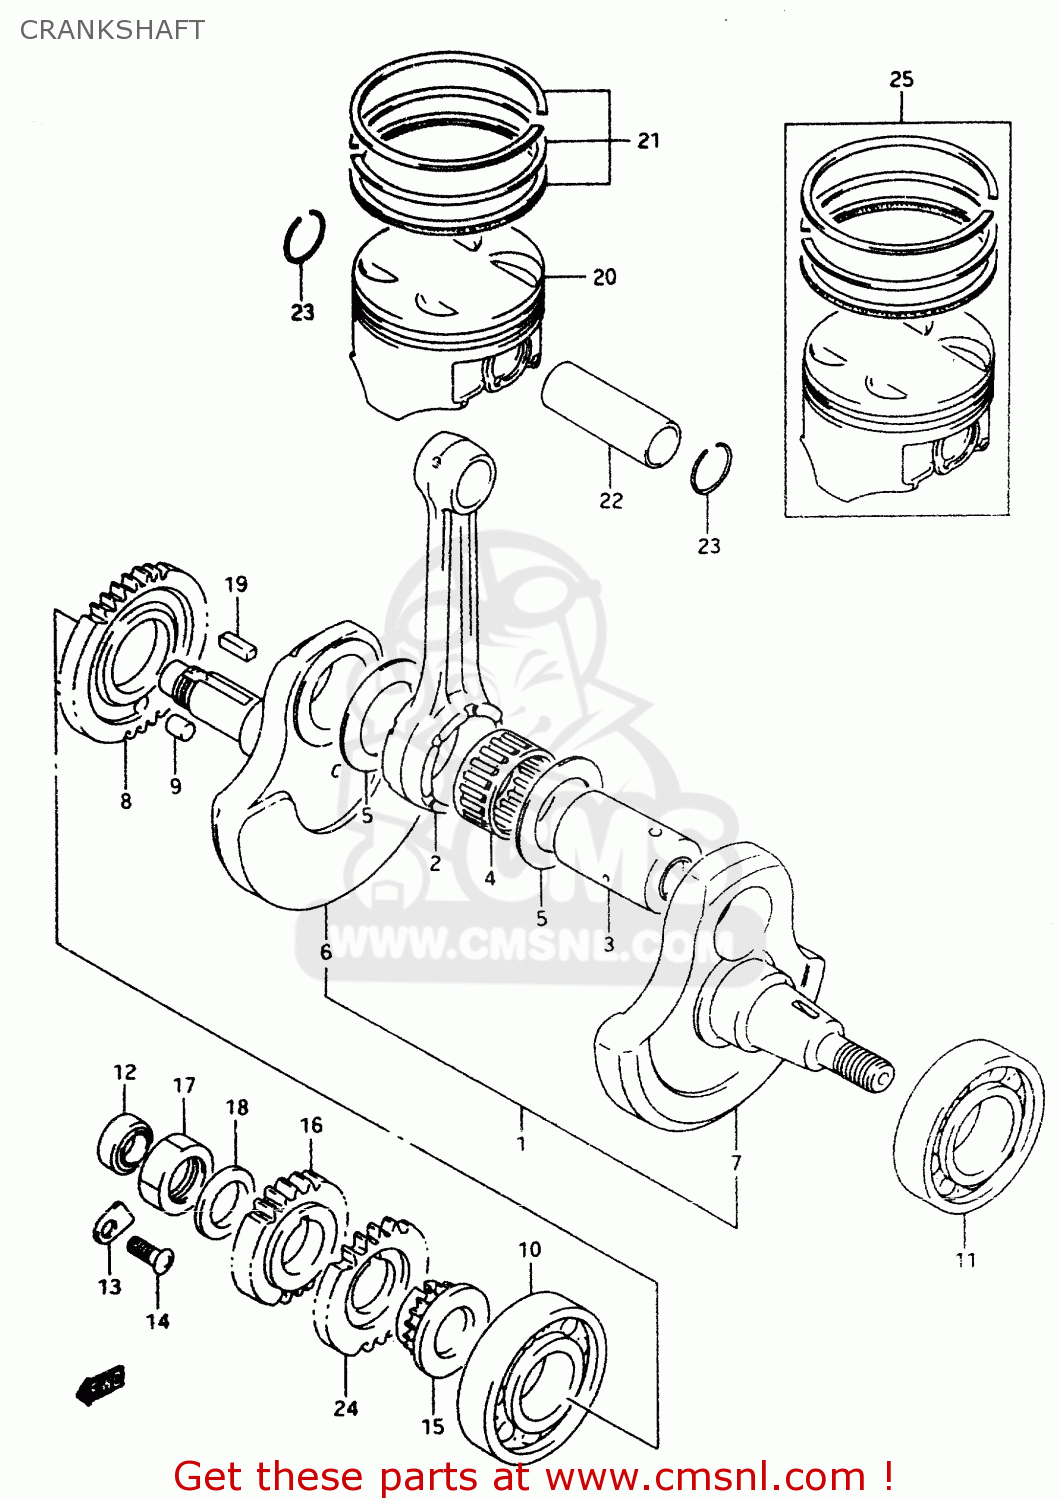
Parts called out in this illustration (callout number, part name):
1	CRANKSHAFT ASSY
2	ROD,CONNECTING
3	PIN COMP,CRANK
4	BEARING(34X43X22)
5	WASHER(34X52X1)
6	CRANKSHAFT,R
7	CRANKSHAFT,L
8	GEAR,CRANK BAL DRIVE(NT:37)
9	PIN
10	BEARING(30X72X19)
11	BEARING(35X72X17)
12	SEAL,OIL(14X24X6)
13	RETAINER,BEARING
14	SCREW
15	SPROCKET,CAM CHAIN DRIVE
16	GEAR,PRIMARY DRIVE (NT:20)
17	NUT
18	WASHER
19	KEY
20	PISTON
21	RING SET,PISTON
22	PIN,PISTON
23	CIRCLIP,PISTON PIN
24	GEAR,OIL PUMP DRIVE (NT
25	PISTON SET(OS:0.5)
26	RING SET,PISTON(OS:1.0)
